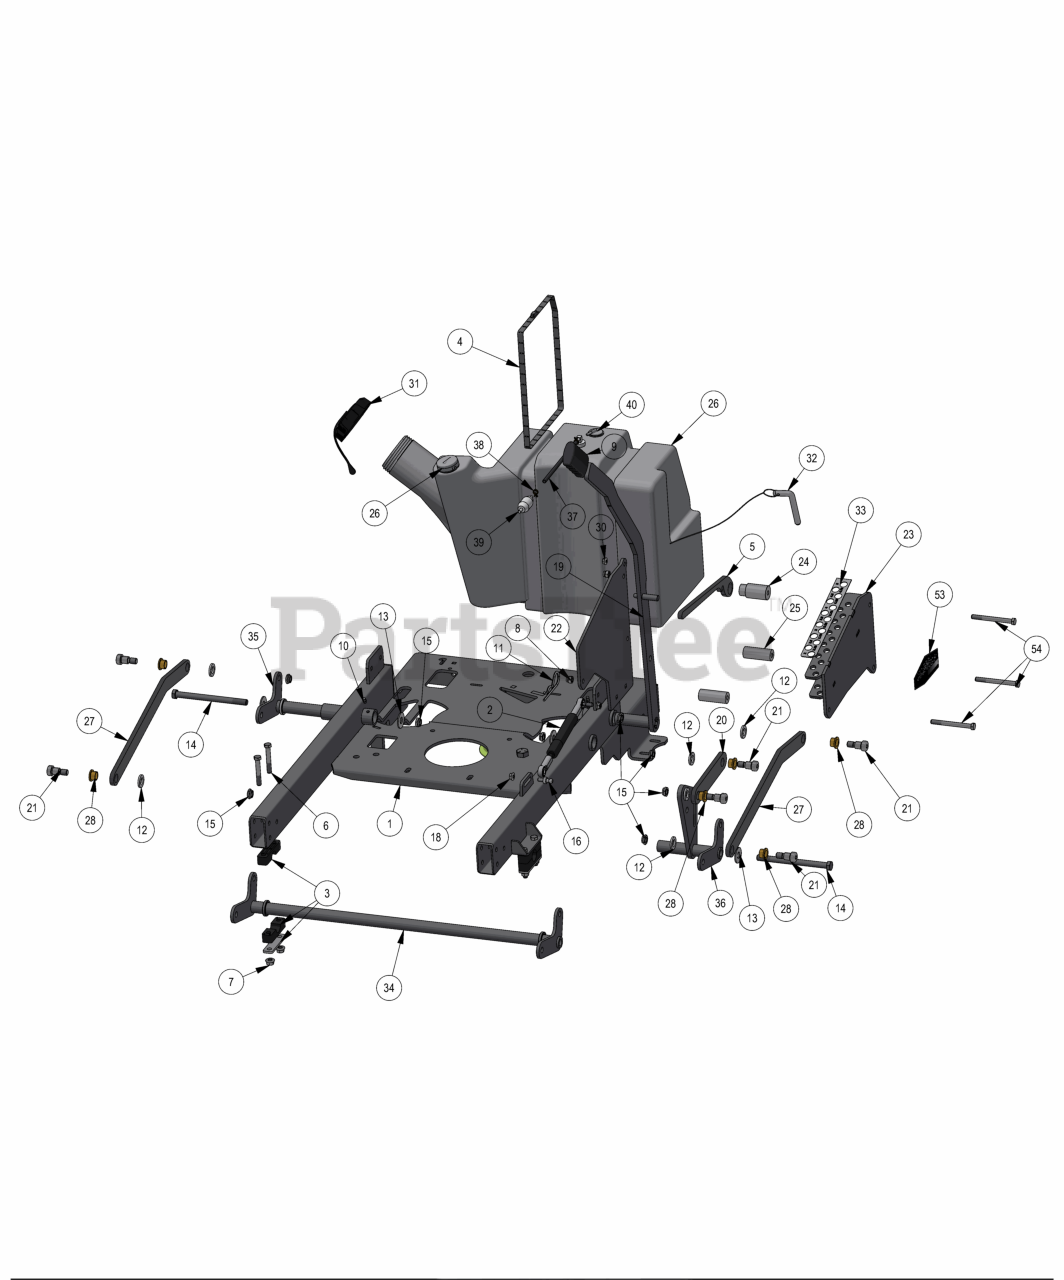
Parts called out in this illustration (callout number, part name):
1	2019 Stand On Frame
2	200 lb Gas Spring- 54" Deck outlaw
3	Pillow Block Kit
4	2019 Stand On Gas Tank Strap
5	2019 Stand On Deck Lever Lock
6	3/8-16 X 2-1/2 HEX CAP SCREW (GR.5) ZINC
7	3/8-16 NYLON INSERT FLANGE LOCKNUT (GR.F) ZINC
8	3/8-16 NYLON INSERT LOCKNUT ZINC
9	2019 Stand On Lift Grip
10	1/4 DRIVE-TYPE STRAIGHT GREASE FITTING (NO BALL) ZINC
11	Revolt Cotter Pin for 7/8" to 1" shank
12	.635 ID X 1.120 OD X .140 THICK FLAT WASHER NYLON
13	1/2 F/W USS (1-3/8" OD) ZINCC
14	1/2-13 X 6 1/2 HEX CAP SCREW (GR.5) ZINC
15	1/2-13 NYLON INSERT JAM LOCKNUT ZINC
16	10mm Damper Ball Stud-Steering
18	5/16-18 HEX SERRATED FLANGE NUT HARD/ZINC
19	2023 Lift Lever Weldment
20	2023 lever secondary linkage
21	5/8 X 5/8 SOCKET SHOULDER BOLT ZINC YELLOW
22	2023 Stand On Inner Adjustment Plate
23	2023 Stand On Outer Adjustment Plate weldment
24	Stand On Spacer 2.5'' With shoulder
25	Stand On Spacer 2.5''
26	2023 revolt_Fuel_ tank
27	2023 Stand-on Actuator Linkage
28	.627 ID X .753 OD X .500 LGTH X 1.000 FLG OD X .094 FLG THICK
30	1/4-20 NYL INSERT FLANGE LOCKNUT ZINC
31	2023 Revolt fuel cap
32	2023 stand on Height Adj Pin
33	2023 Revolt Deck Height decal
34	2023 Stand On Front Actuator
35	2023 Stand On Actuator Rear RH
36	2023 Actuator rear_LH
37	1/4" Fuel Line Hose
38	1/4 Fuel Hose Clamp
39	27HP Kohler Fuel Filter
40	Rollover Valve W/Grommet
53	Revolt Deck Height Decal
54	3/8-16 X 3-3/4 HEX CAP SCREW (GR.5) ZINC
